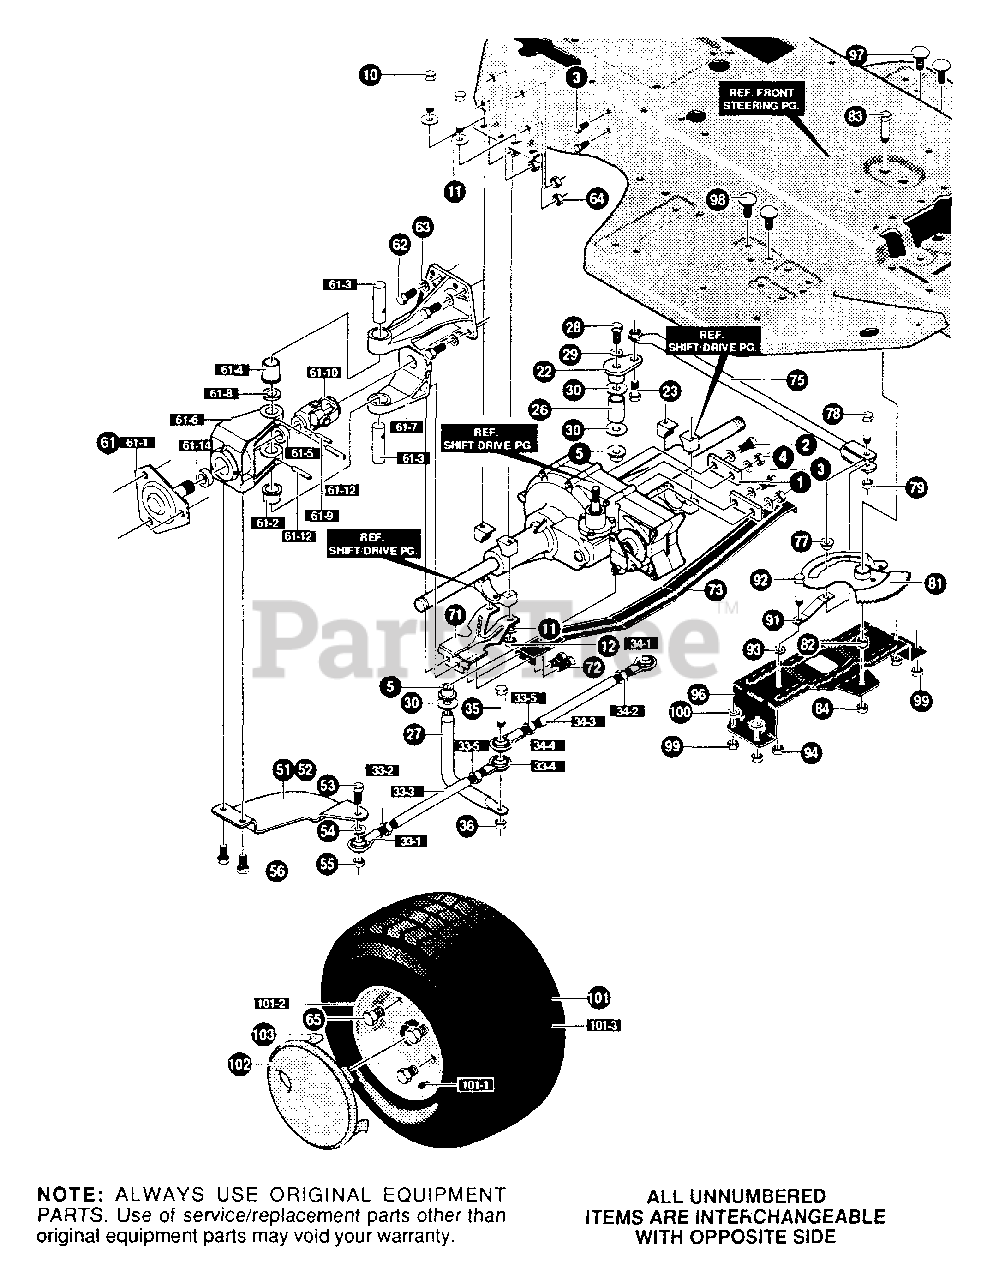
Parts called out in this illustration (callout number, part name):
1	BRACKET, REAR PIVIOT HYDRO
2	SCREW, 1/4-20X .75 WAHHTAP
3	WASHER, REGSPTLK .263X.49X.07
4	NUT 1/4-20 REGHEX
5	BEARING SPINDLE FR W/HOLE
10	SCREW, 5/16-18X2.50 HHC
11	WASHER, FLAT .344X.69X.065
12	NUT, 5/16-18 HWDFLCTRLK
22	PIVOT, STEERING
23	BOLT, .562X .340 HHSH 3/8-24
26	SPACER, STEERING SHAFT HYDRO
27	SHAFT, STEERING PIVOT HYDRO
28	SCREW, 5/16-24X1.00 HHC
29	WASHER, FLAT .333X.87X.119
30	WASHER, FLAT .765X1.19X.048
33	TIE ROD, ASSY RH EUR04WS&LFHYDR
33-1	BALL JOINT LH 3/8-24
33-2	NUT, 3/8-24 REGHEXJAM
33-3	ROD, TIE 1/2"D X 6.75LG
33-4	BALL JOINT, RH 3/8-24
33-5	NUT, 3/8-24 LH THD REGHJAM
34	TIE ROD, ASSY LH EURO 4WS&LFHYDR
34-1	BALL JOINT LH 3/8-24
34-2	NUT, 3/8-24 REGHEXJAM
34-3	ROD, TIE 1/2"D X 10.91 LG ZINC
34-4	BALL JOINT, RH 3/8-24
34-5	NUT, 3/8-24 LH THD REGHJAM
35	SCREW, 3/8-24X1.75 HHC
36	NUT 3/8-24 HXCTRLK
51	ARM REAR WHL STR (FER) R.H
52	ARM, REAR WHEEL STEER L.H
53	SCREW, 3/8-24X1.25 HHC
54	WASHER, REGSPTLK .393X.68X.10
55	NUT, 3/8-24 HXCTRLK
56	SCREW, 3/8-16X1.00 WAHHTAP BLK
61	U-JOINT, 4-WS HEAVY DUTY
61-1	HUB ASSEMBLY HEAVY
61-2	BEARING, FLSH .752 ID X .937OD X .75
61-3	PIN, STEERING HINGE
61-4	BEARING, FLSH
61-5	BEARING BALL 6203-2AA-3/4
61-6	BRACKET, STR PIVOT 6204 BEARING
61-7	BRACKET, STR PIVOT
61-8	WASHER, FLAT .765 X 1.25 X .042
61-9	PIN, GROOVED .250 DIA X 1.50LG
61-10	U-JOINT ASSEMBLY W/ZERK (LONG)
61-12	PIN SPRING .250 DIA X 1.50LG HVPL
61-14	BEARING, BALL 6204-2AA-7/8
62	SCREW 5/16-18X1.00 HHC
63	WASHER, FLAT .344X.69X.065
64	NUT 5/16-18 REGHEXCTRLK
65	SCREW, 1/2-20X .50 HHC
71	BRKT X-AXLE MTG 4WS HYDRO
72	SCREW, 5/16-18X.75 WAHHTAP
73	BRACKET HYDRO 4WS SUPPORT
75	ROD R WHL STR 4WS (HYDRO)
77	CAM YOKE ROLLER
78	BOLT, .625 X1.175HHSH
79	NUT, 1/2-20 REGHXCTRLK
81	ASSY SECTOR GEAR 4WS
82	BRNG SLEV IDX ODX
83	SCREW 1/2-20X2.50 HHC
84	NUT, 1/2-20 REGHXCTRLK
91	FOLLOWER, ROLLER
92	BOLT .265X .800 HHSH 3/8-24
93	WASHER, FLAT .375X.88X.082
94	NUT, 3/8-24 HXCTRLK
96	PLATE, PIVOT STEERING EURO
97	SCREW, 5/16-18X.50 WAHHTAP
98	SCREW, 5/16-18X.75 WAHHTAP
99	NUT, 5/16-18 REGHEXCTRLK
100	WASHER, FLAT .375X.88X.082
101	TIRE & RIM,20X10.00-8 WHITE
101-1	VALVE STEM
101-2	RIM, WHEEL
101-3	TIRE 20X10X8
102	HUB CAP, 8" EURO GREY
103	CLIP,HUBCAP TINN #C25467-017-4
